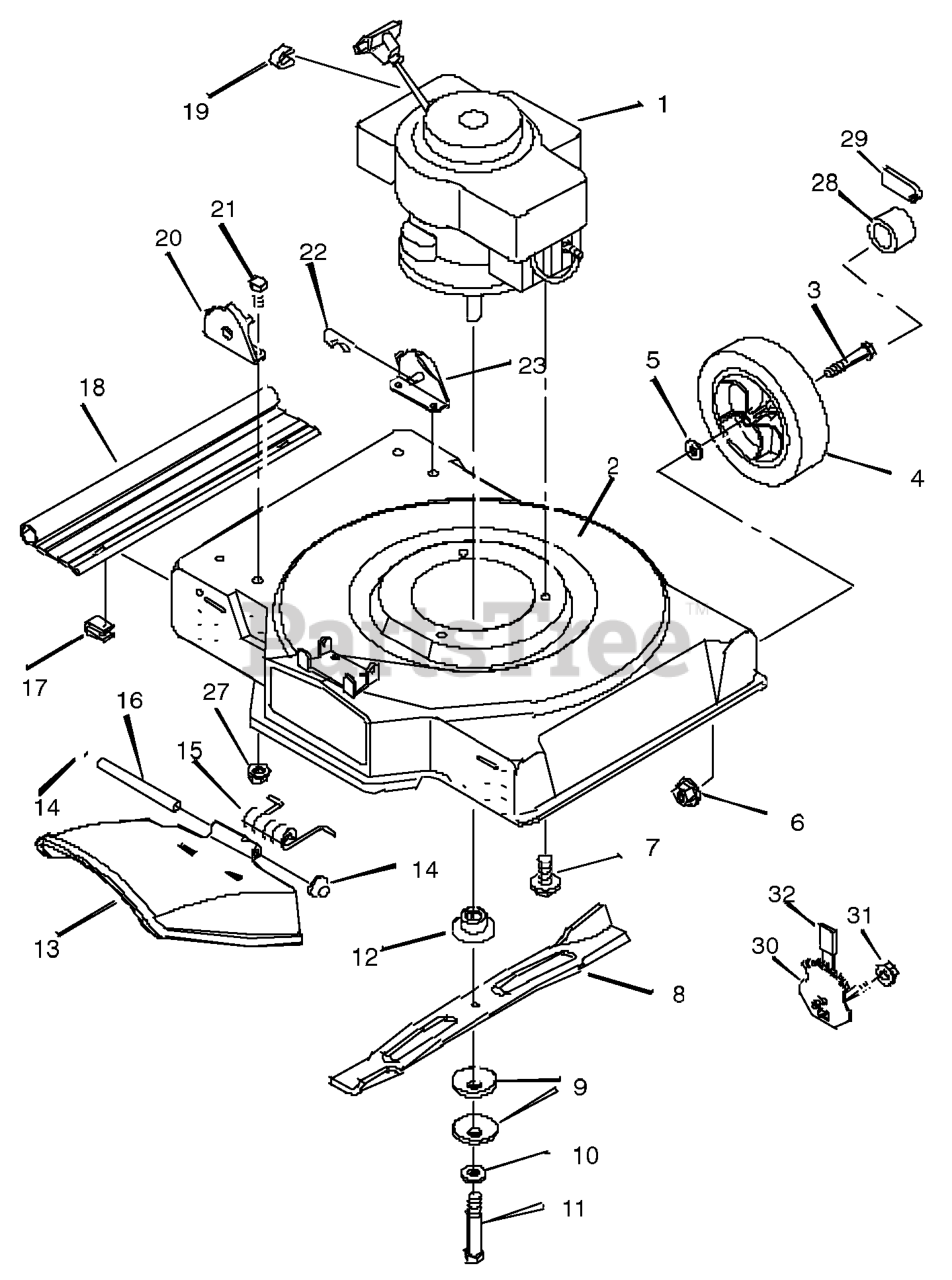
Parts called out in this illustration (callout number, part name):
1	Engine *
2	Housing
3	Bolt, Axle
4	Wheel and Tire *
6	Locknut, Flange
7	Bolt, Engine
9	Washer, Belleville
11	Bolt, Hex
12	Adapter, Blade
13	Deflector, Chute
14	Push- On Cap
16	Pin, Pivot
17	Retainer
18	Deflector, Rear
19	Stop, Rope
20	Bracket, Right Handle
22	Pin, Hair
23	Bracket, Left Handle
27	Nut
28	Hub Cap
29	Hub Cap
30	Adjuster, Height
31	Locknut, Flange
